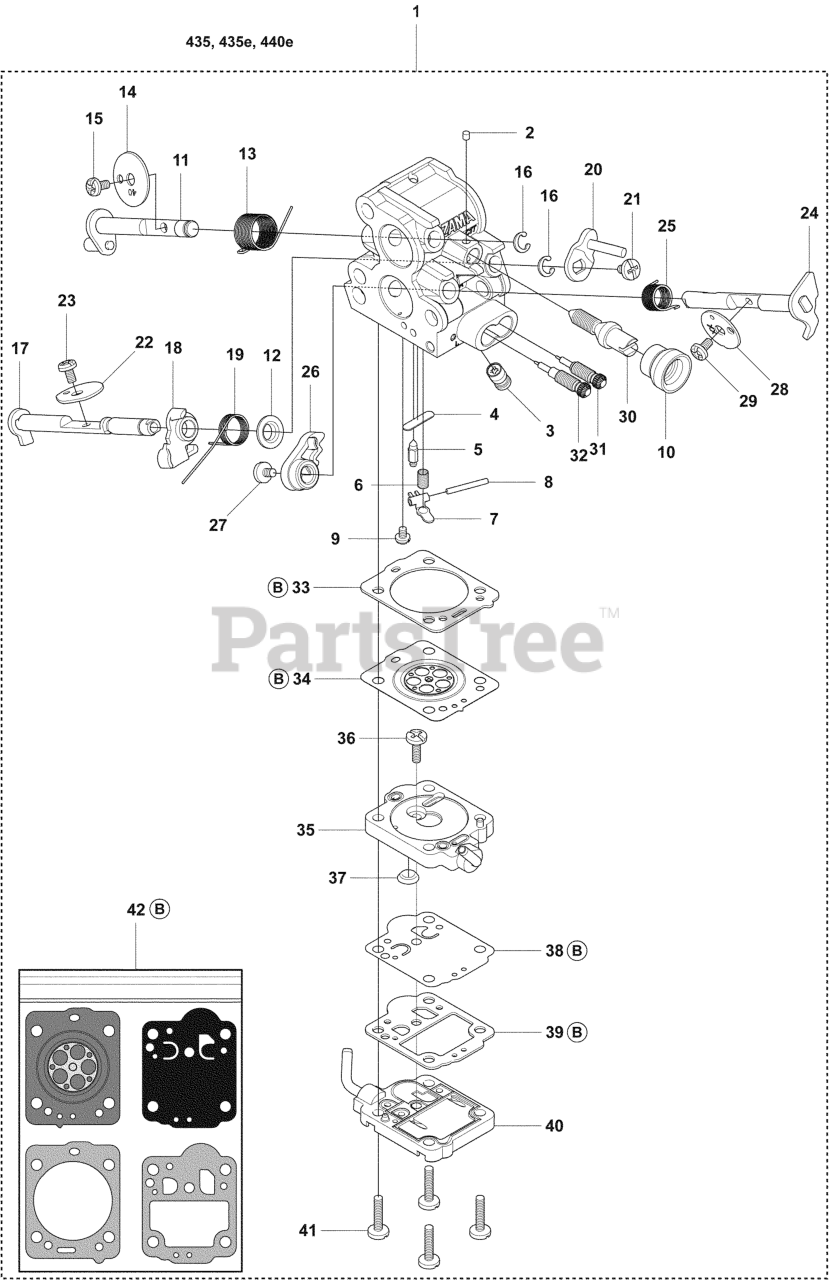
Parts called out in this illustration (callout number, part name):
1	CARBURETOR
2	PLUG
3	NOZZLE ASSY
4	PLUG
5	INLET NEEDLE
6	SPRING
7	LEVER
8	PIN RETAINING SCREW
9	SCREW
10	CAP ZAMA 0051034
11	SHAFT ASSY
12	COLLAR ZAMA 005020
13	SPRING
14	VALVE
15	SCREW
16	E RING
17	CHOKE SHAFT ASSY
18	LEVER
19	SPRING
20	LEVER
21	SCREW
22	VALVE
23	SCREW
24	THROTTLE SHAFT ASSY
25	SPRING
26	LEVER
27	SCREW
28	VALVE
29	SCREW
30	SCREW
31	SCREW
32	SCREW
33	GASKET
34	DIAPHRAGM
35	BODY
36	SCREW
37	STRAINER
38	DIAPHRAGM
39	GASKET
40	COVER
41	SCREW
42	GASKET KIT
